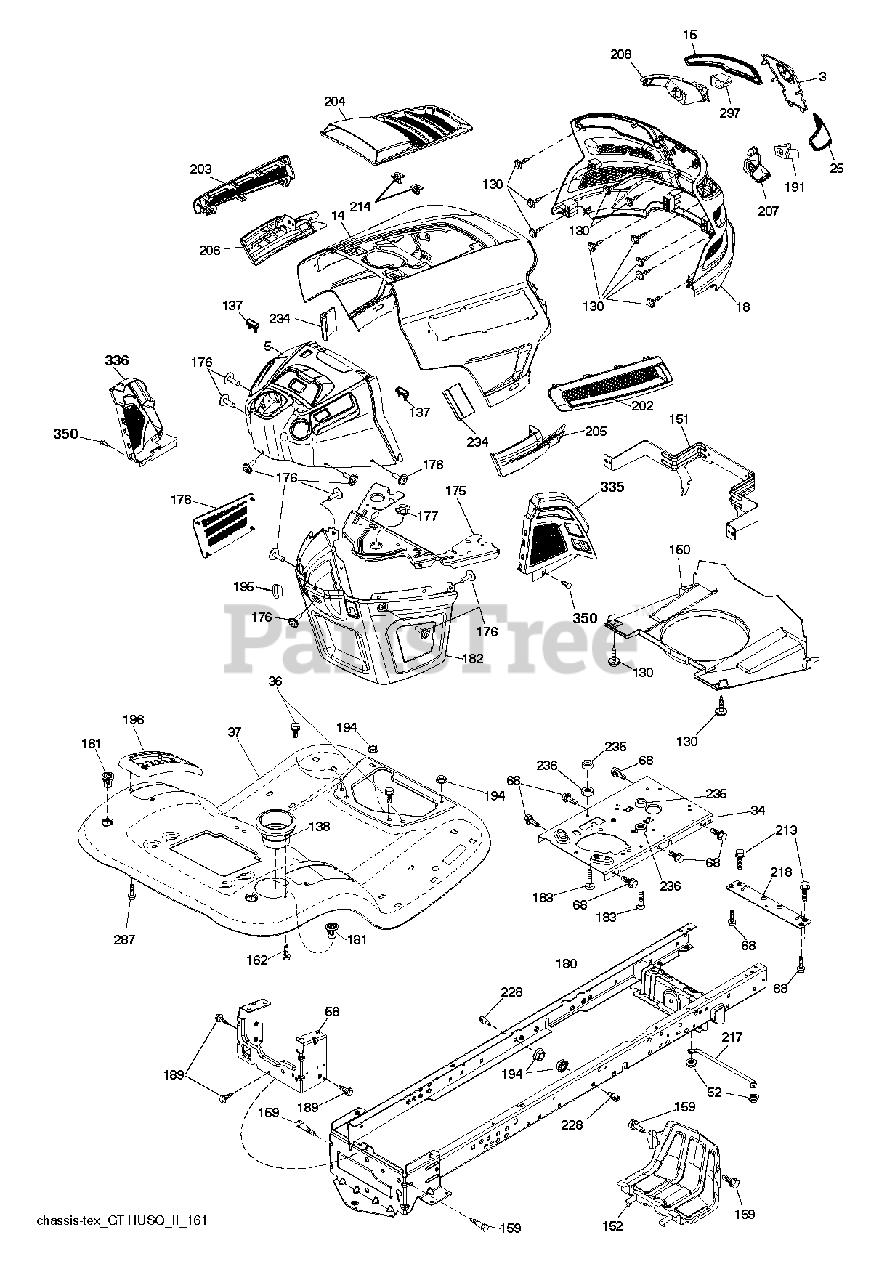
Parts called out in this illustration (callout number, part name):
3	APPLIQUE.SUBASM.GT.HUSQ.II
5	DASH.W/O.BUMPERS.RS.
14	HOOD.ASM.HUSQVARNA.GT.TEX.ORAN
15	LENS.HEADLIGHT.LH.GTII.2011
18	GRILLE.SUBSTRATE.2011.
25	LENS.HEADLIGHT.RH.GTII.2011
34	PLATE.ENGINE.WELDED.CHASSIS
36	SCREW 5/16"
37	FENDER.TLT.PDL.CNTRL.W/CPH.ORG
52	LOCKNUT
58	DRAWBAR UPPER 2PC SMALL FENDER
68	SCREW LT
130	SCREW.#10 X 0.750.BOS
137	BUMPER DASH
138	HOLDER.CUP.LT.GREY
150	AIR.DUCT.GTV2(2.54"RING HEIGHT
151	BRACKET.PIVOT.HOOD.GT.HUSQ.II
152	SHIELD.BROWNING.PNT.GT.V2
159	SCREW, 3/8-16X3/4
162	SCREW.HI-LO.CONSOLE
175	PLATE.CROSSMEMBER.HUSQ
176	SCREW.#10-24X5/8.RN.QU
177	BUSHING STEERING
178	CARGO.ASM.NET.TXGT.W/C
180	CHASS.WLDMNT.TL.12GA/2P.48/54
181	BUSHING.MNT.FEND.CRGO.TEX.49
182	DASH.LOWER.COMMON.12V.ADAPTOR
183	BOLT.5/16-18X1-1/4 FULL THD
189	SCREW
191	INSERT.REFLECTIVE.RH.HUSQ.GTII
194	NUT LOCK HEX FLANGE 5/16-18
195	PLUG.HOLE.DASH.LOWER.12V.BLK
196	DECKLFT.CONSOL FULL ASSM GREY
202	VENT.SIDE.RH.GT.HUSQ.II.
203	VENT.SIDE.LH.GT.HUSQ.II.498
204	VENT.TOP.HUSQ.GT2
205	SIDE.TRIM.RH.GT.HUSQ.II
206	SIDE.TRIM.LH.GT.HUSQ.II.GRAY
207	BEZEL LIGHT.RH.GT.II.MYLAR
208	BEZEL LIGHT.LH.GT.II.MYLAR
213	BOLT
214	CLIP.RETAINER.TINNER.
217	ROD.PIVOT.HOOD
218	X-PIECE.HOOD.STOP.NON/
228	STUD.FASTNER.W/ANTI-ROTATE
234	BUMPER.HOOD.TEX.HUSQVARNA
235	SPACER FENDER
236	NUT.CENTERLOCK.5/16-
287	SCREW 1/4X20
297	INSERT.REFLECTIVE.LH.HUSQ.GTII
335	COVER.LOWER.DASH.RH.BLACK
336	COVER-LH.LOWER.DASH.GT2.BLACK
350	CLIP.X-MAS.TREE
